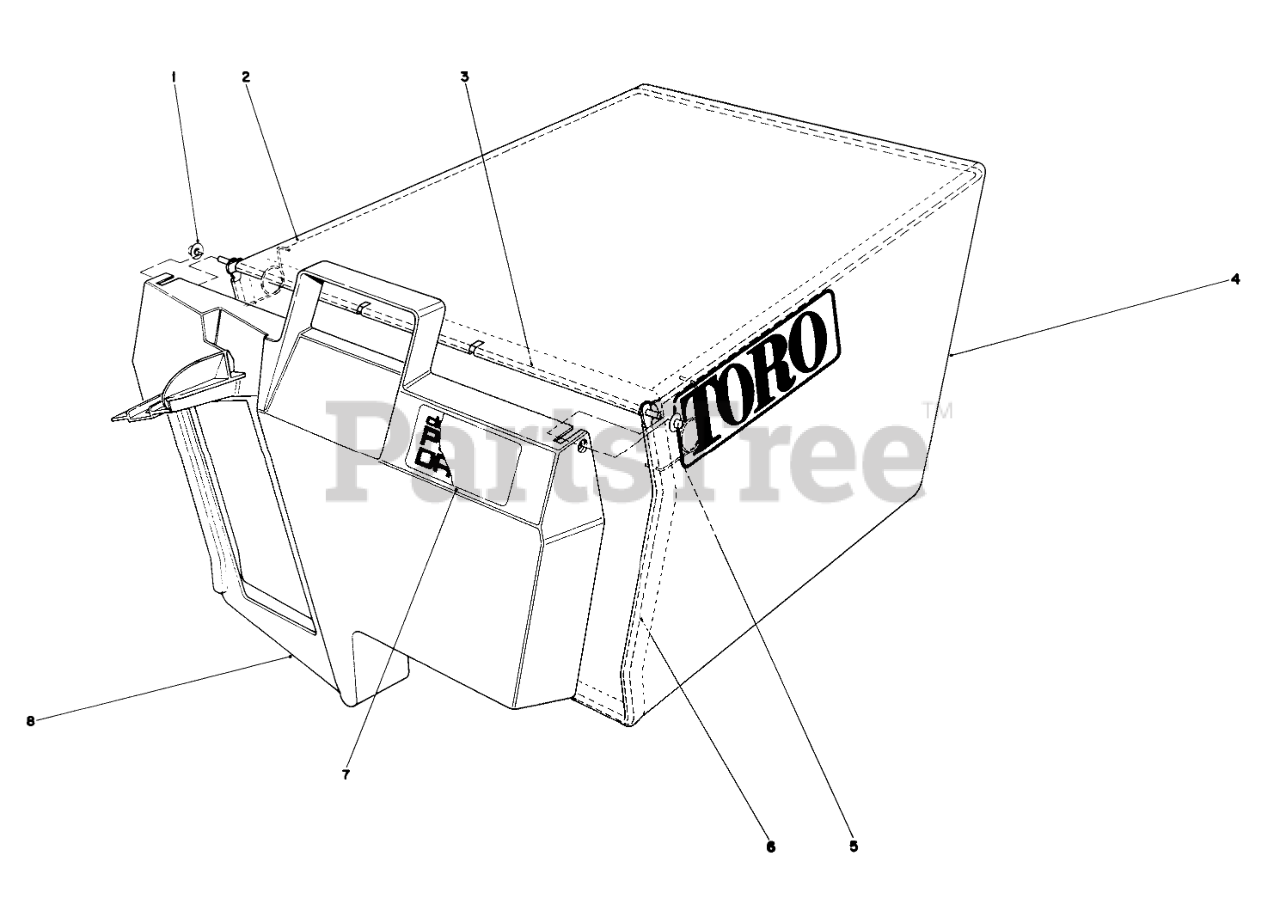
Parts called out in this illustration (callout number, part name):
1	NUT-PUSH
2	FRAME-BAG, UPPER
3	HINGE-DOOR, BAG
4	Bag
5	SPRING
6	FRAME-BAG
7	BAG DOOR DECAL
8	DOOR-BAG
